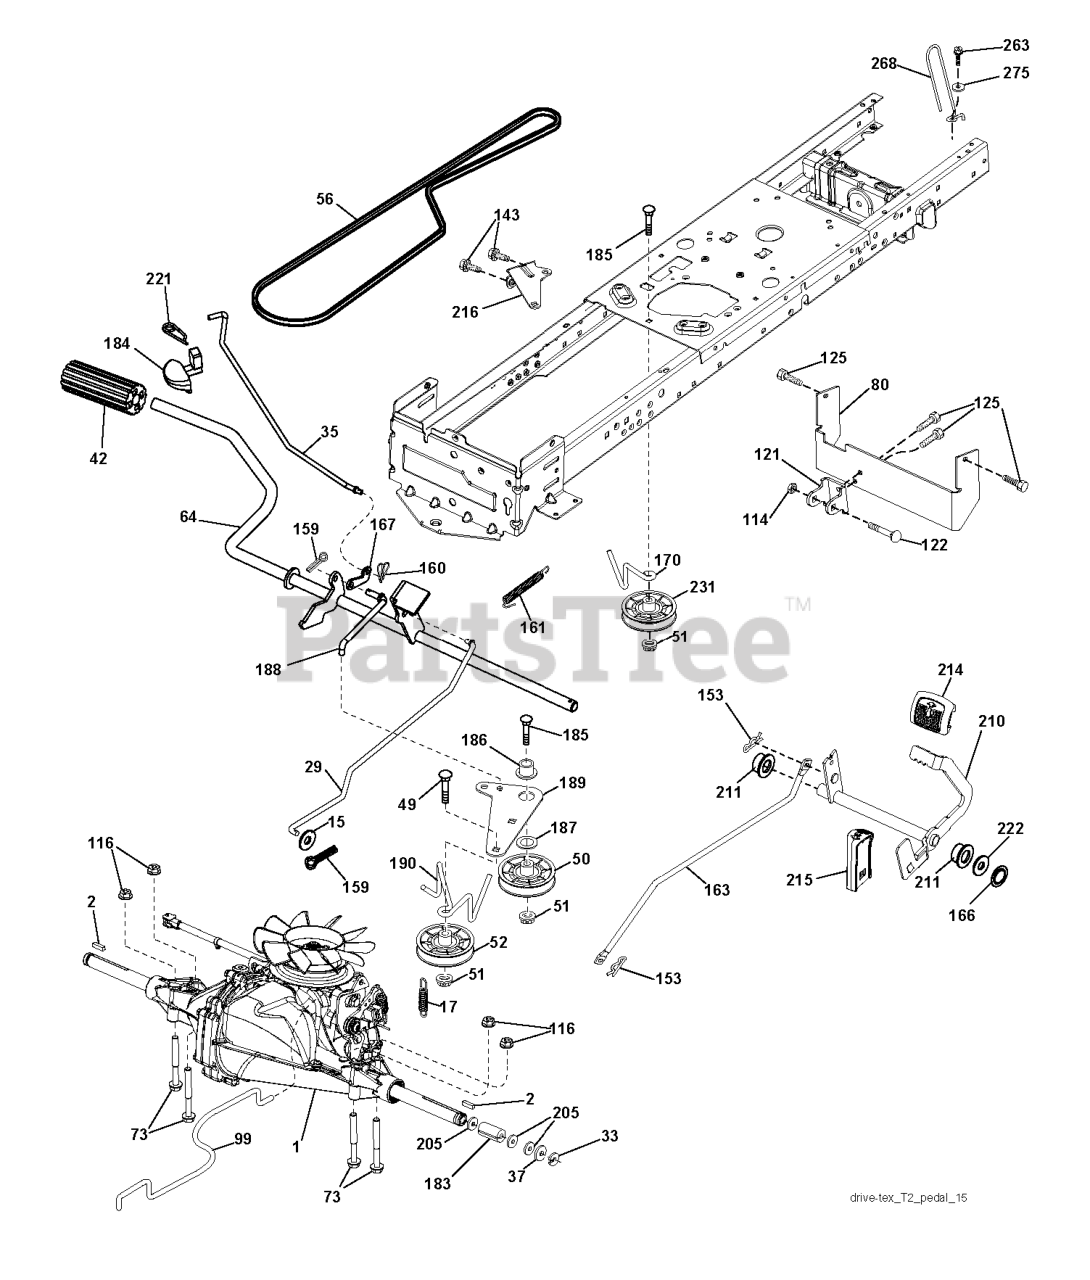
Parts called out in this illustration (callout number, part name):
2	SQUARE KEY
15	WASHER
17	SPRING.BRAKE.HG3000/3500
29	ROD.BRAKE.T2.TEX
35	ROD.CNTRL.PARK.PREDATOR.LT.TEX
42	PEDAL COVER T
50	IDLER.FLAT.910.OFFSET
51	NUT LOCK FLG 3/8-16 UNC
52	IDLER.V-GROOVE.910.OFFSET
64	SHAFT.ASM.PEDAL.BRK.CNTR
73	BOLT HEX 5/16-18 GR 5
80	RP.STRAP.TORQUE.FS.T2
99	ROD.ASM.BYPASS.SPRING.T2.FS
114	NUT.71038.31-18.HEX.NYLOCK
116	NUT LOCK HEX FLANGE 5/16-18
121	BRACKET STRAP TORQUE
122	BOLT.5/16-18X2.5
125	SCREW
143	Screw 5/16-18 x 1/2 Hex, Self Tapping 5/16-18 x 1/2
153	RETAINER M
159	COTTER PIN
160	RETAINER CLIP
161	SPRING, RETURN LT
163	ROD.CONTROL.PCH.T2.TEX
166	NUT.PUSH.625.2006
167	LATCH.BRAKE.SPRING
170	KEEPER.CENTER SPAN.1.688
183	SPACER, AXLE PVST
184	HANDLE PARKING BRAKE
186	SPACER.RETAINER
187	WASHER 12/32X2X10GA
188	RP.LINK.CLUTCH.GROUND.DRIVE
189	BELLCRANK.GROUND.DRIVE.TEX.
190	KEEPER.BELLCRANK.DRIVE
210	ROCKER.ASM.PEDAL.CONTR
211	BEARING.NYLON
214	PEDAL.FORWARD.TEX.GT.4
215	PEDAL.REVERSE.TEX.GT.4
216	BRACKET.PULLEY.IDLER.W/TEX
221	RETAINER.SPRING.CLIP.H
222	WASHER 21/32 X 1-1/4 X 10 GA.
231	IDLER.V-GROOVE.1.688.OFFSET
263	SCREW, 3/8-16X3/4
268	WASHER
275	GUARD MUFFLER
